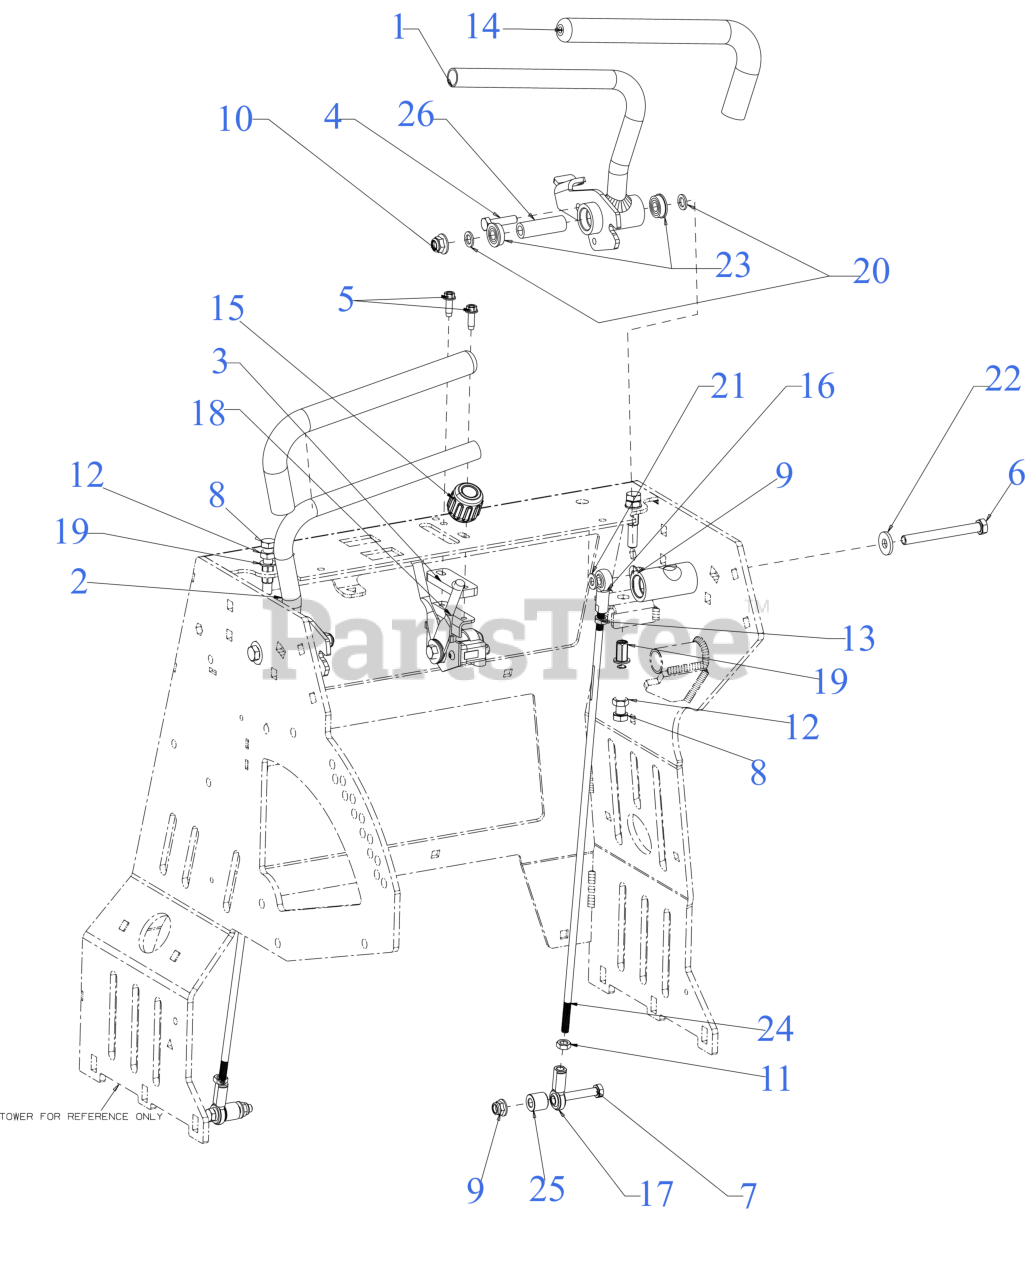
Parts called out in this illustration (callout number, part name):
1	CONTROL HANDLE (LH)
2	CONTROL HANDLE (RH)
3	THROTTLE CABLE SPACER
4	SCREW 5/16-18 x 1.25 GR5
5	SCREW 1/4-20 x .750
6	SCREW 3/8-16 x 3.50 GR5
7	SCREW 5/16-18 x 1.75 GR5
8	SCREW 3/8-16 x 2 GR5
9	FLANGE LOCK NUT 5/16-18
11	HEX JAM NUT 5/16-24 GR5
12	HEX NUT
13	HEX JAM NUT 5/16-24 GR 5
14	GRIP .75 ID X 1.00 OD
15	BALL KNOB
16	ROD END 5/16 ID
17	END ROD- 5/16 (LH)
18	ELECTRONIC THROTTLE CONTROL
19	RIV NUT 3/8-16
20	FLAT WASHER
21	FLAT WASHER
22	WASHER
23	FLANGE BEARING
24	CONTROL ROD
25	SPACER .34 x .75 x .63 LG
26	SPACER .379 x .63 x 1.957
